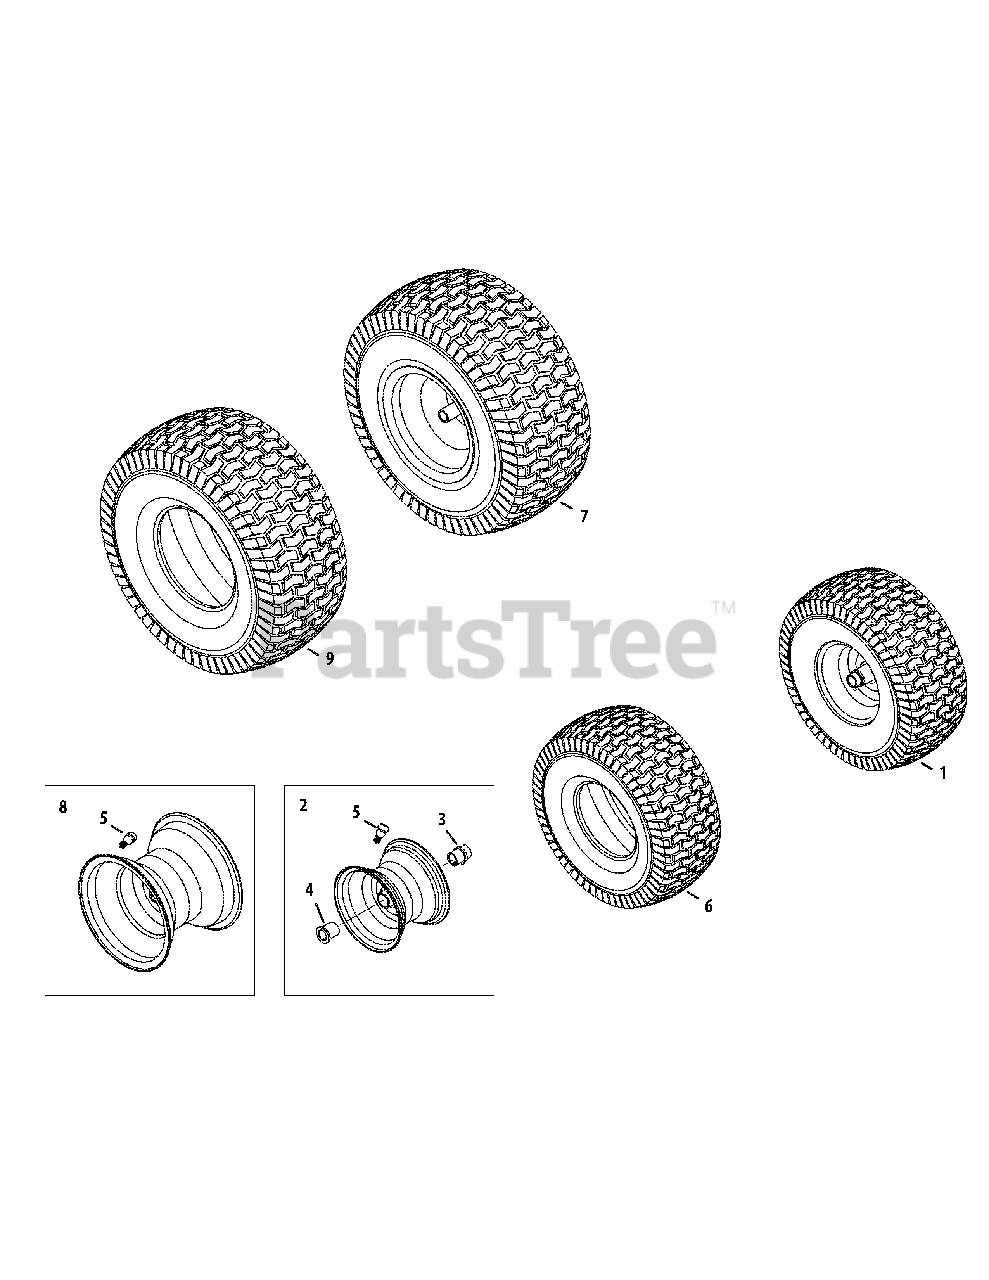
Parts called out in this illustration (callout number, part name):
1	Wheel Ass’y, Complete, 15 x 6 x 6
2	Rim Ass’y, 6.0 x 4.5, w/ Bearings
3	Bearing, Flange, .760 ID w/ Fitting
4	Bearing, Flange, .760 x 1.00 x 1.20
5	Valve, Tubeless Air
6	Tire, 15 x 6 x 6 Sq Shoulder
7	Wheel, Complete, 20 x 8 x 8
8	Rim, 8.0 x 7.0 x .750 ID
9	Tire, 20 x 8 x 8 Sq Shoulder
